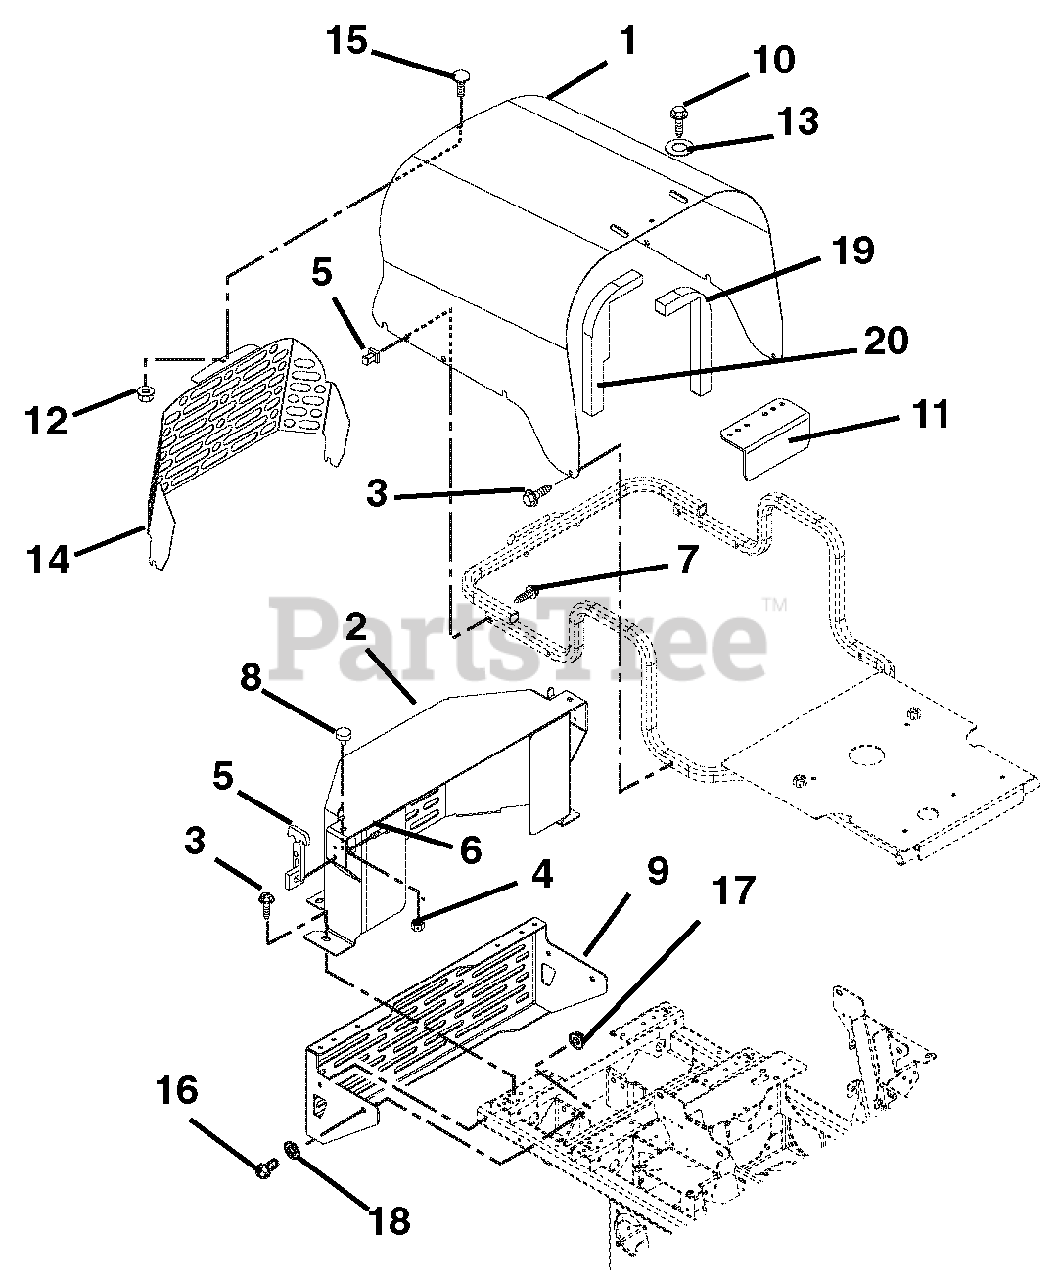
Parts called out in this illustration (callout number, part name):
1	L/C HOOD - RED
2	DIESEL BELT GUARD - BLACK
3	@SCR-TAP .38-16X.75 HWH TR YWZ
4	@NUT-SPNLK-FLG .312-18 YWZC
5	LATCH, RUBBER
6	@SCR-MCH 10-24X.50 HWH YWZC
7	@SCR-MCH 10-24X1.50 HWH YWZC
8	BUMPER, RUBBER
9	WMT, BUMPER
10	@SCR-TAP .25-20X.50 HWH TR YWZ
11	GUARD, RADIATOR CAP- DIESEL
12	@NUT-LK-TOP-FLG .25-20 YWZC
13	@WSHR-FL-STL.281X.62X.065 YWZC
14	L/C HOOD GUARD - BLACK
15	@BLT-RDHDSQNK .25-20X.50 G5YZ
16	@BLT-HEX .38-16X2.75 GR5 YWZC
17	@NUT-LK-TOP-FLG .38-16 YWZC
18	@WSHR-FL-STL.406X.812X.065 YWZ
19	DAM, LEFT SIDE FOAM AIR
20	DAM, RIGHT SIDE FOAM AIR
